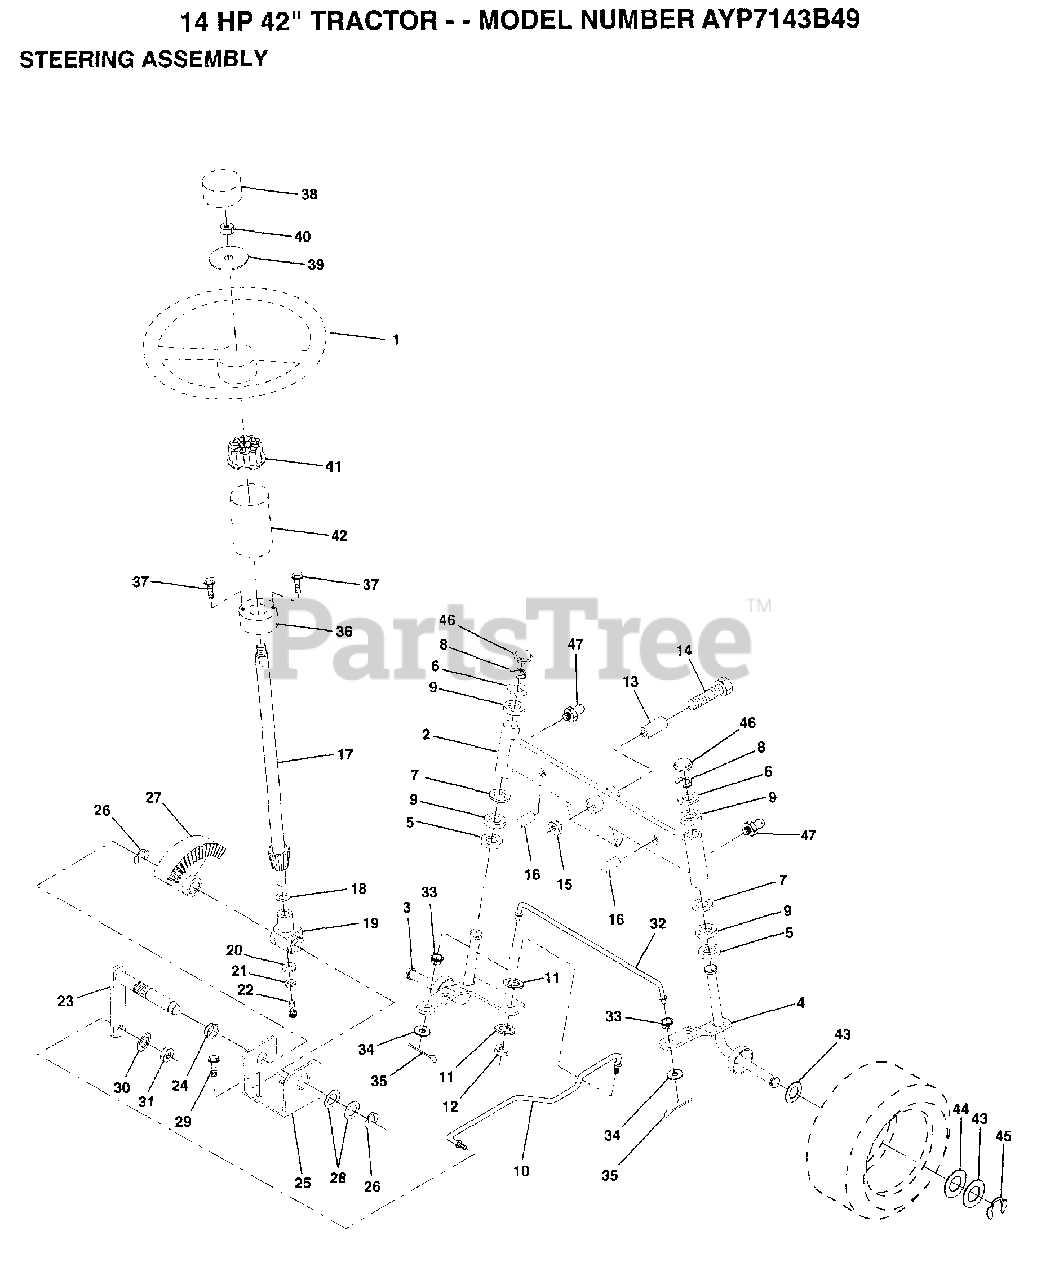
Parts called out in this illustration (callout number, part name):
2	AXLE ASM FRONT
3	SPINDLE LH
4	SPINDLE RH
5	WASHER .T
6	WASHER
7	WASHER
8	RING
9	COL. SRTG. BEAR.
11	LOCKWASHER
13	BEARING
14	BOLT HEX 5/8-11
15	"NUT-LOC,FLANGE LT"
16	AXLE PIN
17	SHAFT ASM
18	THRUST WASHER
19	SUPPORT.SHAFT
21	LOCKWASHER
22	"SCREW,SPECIAL"
24	NYLINER T
25	"BRKT,STEERING"
26	RING
27	GEAR SECTOR
28	WASHER .T
29	SCREW
30	LOCKWASHER
32	TIE ROD
33	BUSHING.DRAGLINK
34	WASHER
35	COTTER PIN
38	ST WHL INSERT CAP
39	WASHER T
40	GRIPCO NUT
41	ADAPTER-WHEEL LT
42	"TUBE, STR SHAFT"
43	WASHER
44	WASHER
45	RING
46	CAP
47	ZERK M
